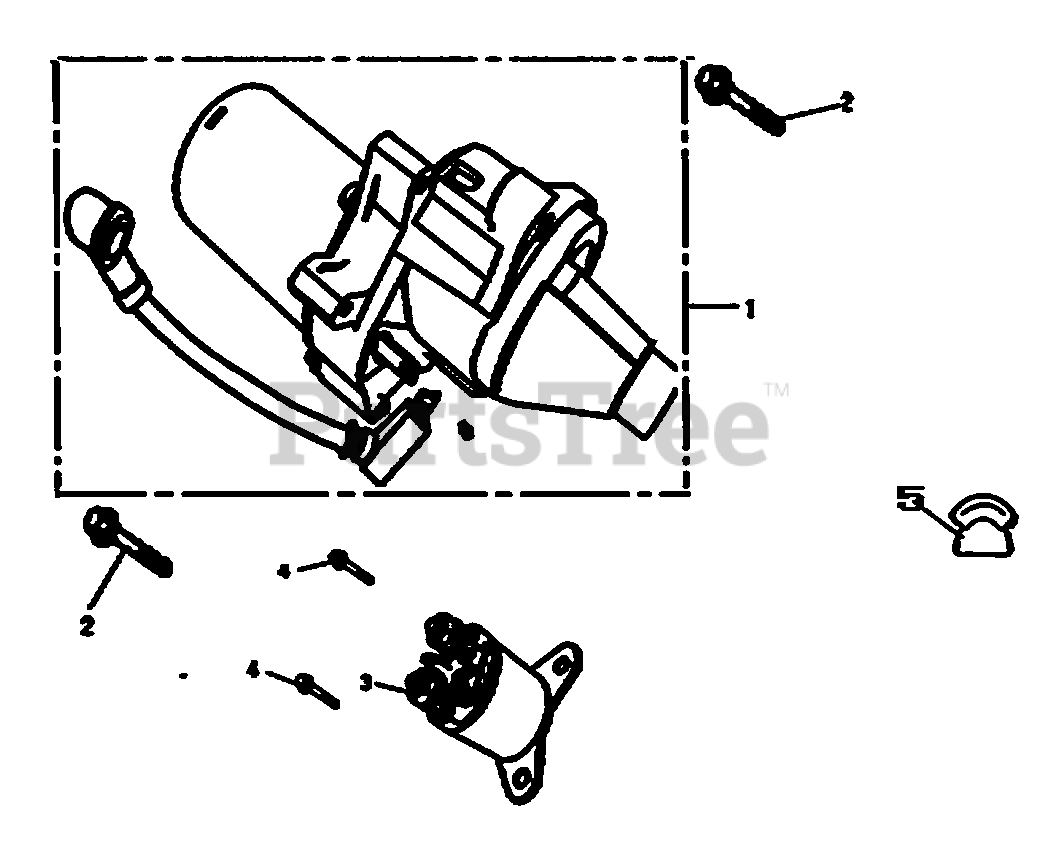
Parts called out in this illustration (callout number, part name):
1	STARTER MOTOR
2	BOLT, FLANGE,
3	CONTACTOR ASSY.
4	BOLT-WASHER
